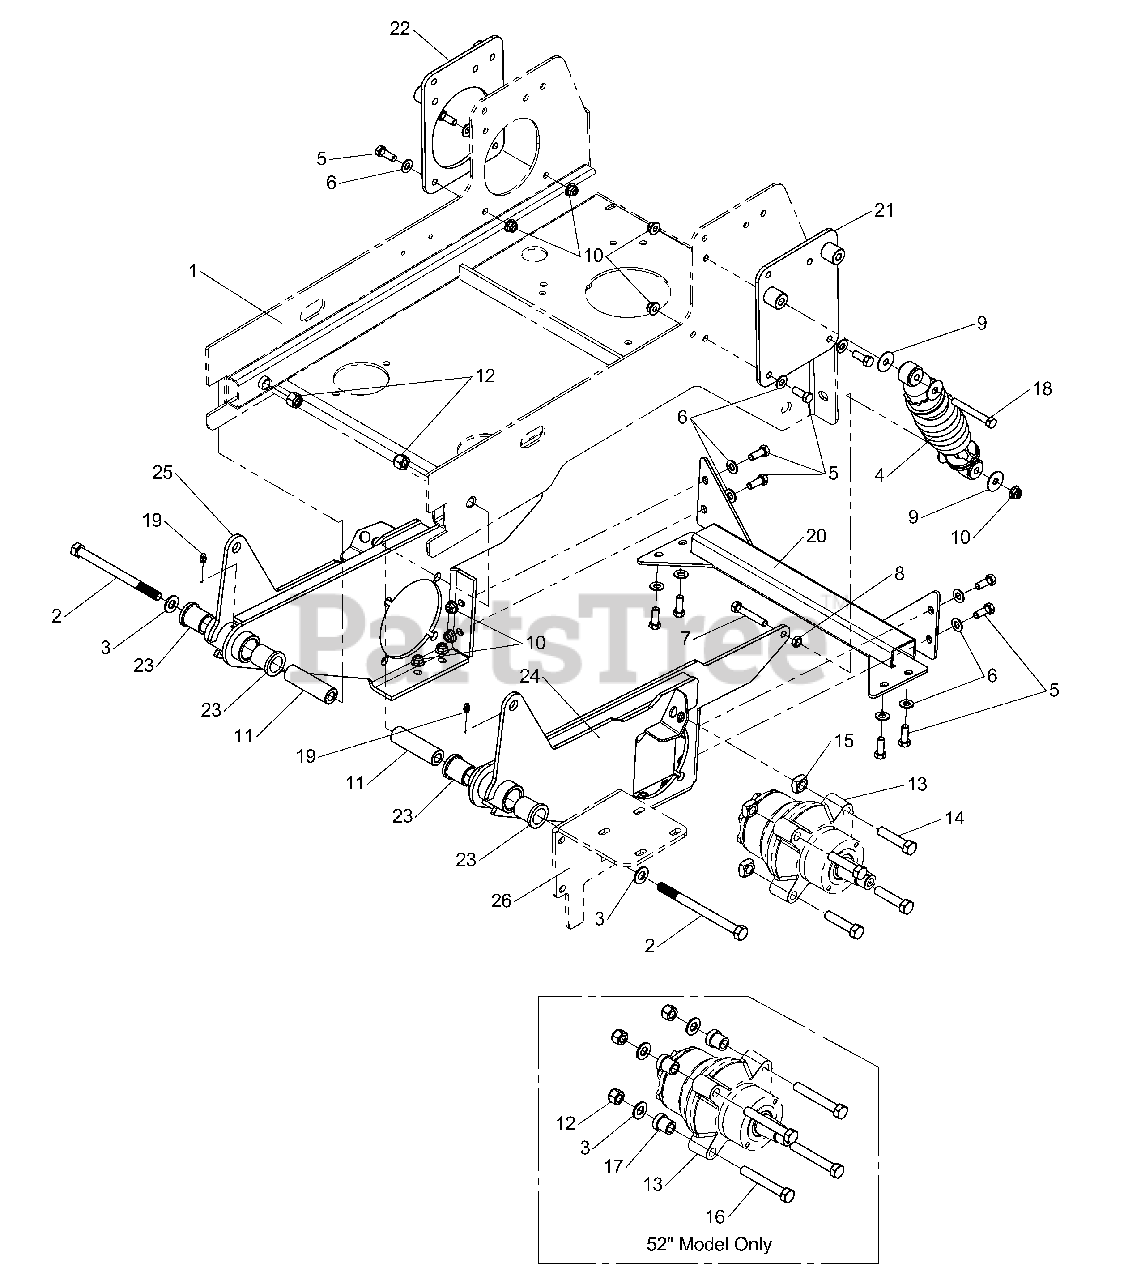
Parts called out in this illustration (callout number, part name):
1	MAIN FRAME (See Main Frame Group)
2	BOLT, 1/2-13 X 6-1/2"
3	WASHER, 1/2" SAE
4	SHOCK ASSEMBLY
5	BOLT, 3/8-16 X 1"
6	WASHER, 3/8" SAE
7	BOLT, 3/8-16 X 2-1/4" TFL
8	NUT, 3/8-16 Hex Jam
9	WASHER, 3/8" FENDER
10	NUT, 3/8-16 Hex Nylock Flange
11	SPACER, .52 X 1.00 X 3.42
12	NUT, 1/2-13 Hex Nylon Lock
13	WHEEL MOTOR
14	BOLT, 1/2-13 X 2-1/4" w/ Loctite Patch
15	NUT, 1/2-13 Square
16	BOLT, 1/2-13 X 3-1/2"
17	SPACER, .53 X 1.00 X 1.00
18	BOLT, 3/8-16 X 3"
19	GREASE FITTING
20	KIT, TIE BAR (Early Models)
20	KIT, TIE BAR (Later Models with ROPS)
21	FRAME SUPPORT, LH
22	FRAME SUPPORT, RH
23	BUSHING, Flange
24	MOTOR MOUNT, RH (Early Models)
24	MOTOR MOUNT, RH (Later Models with ROPS)
25	MOTOR MOUNT, LH (Early Models)
25	MOTOR MOUNT, LH (Later Models with ROPS)
26	TANK MOUNT (See Fuel Tank & Mount Group)
